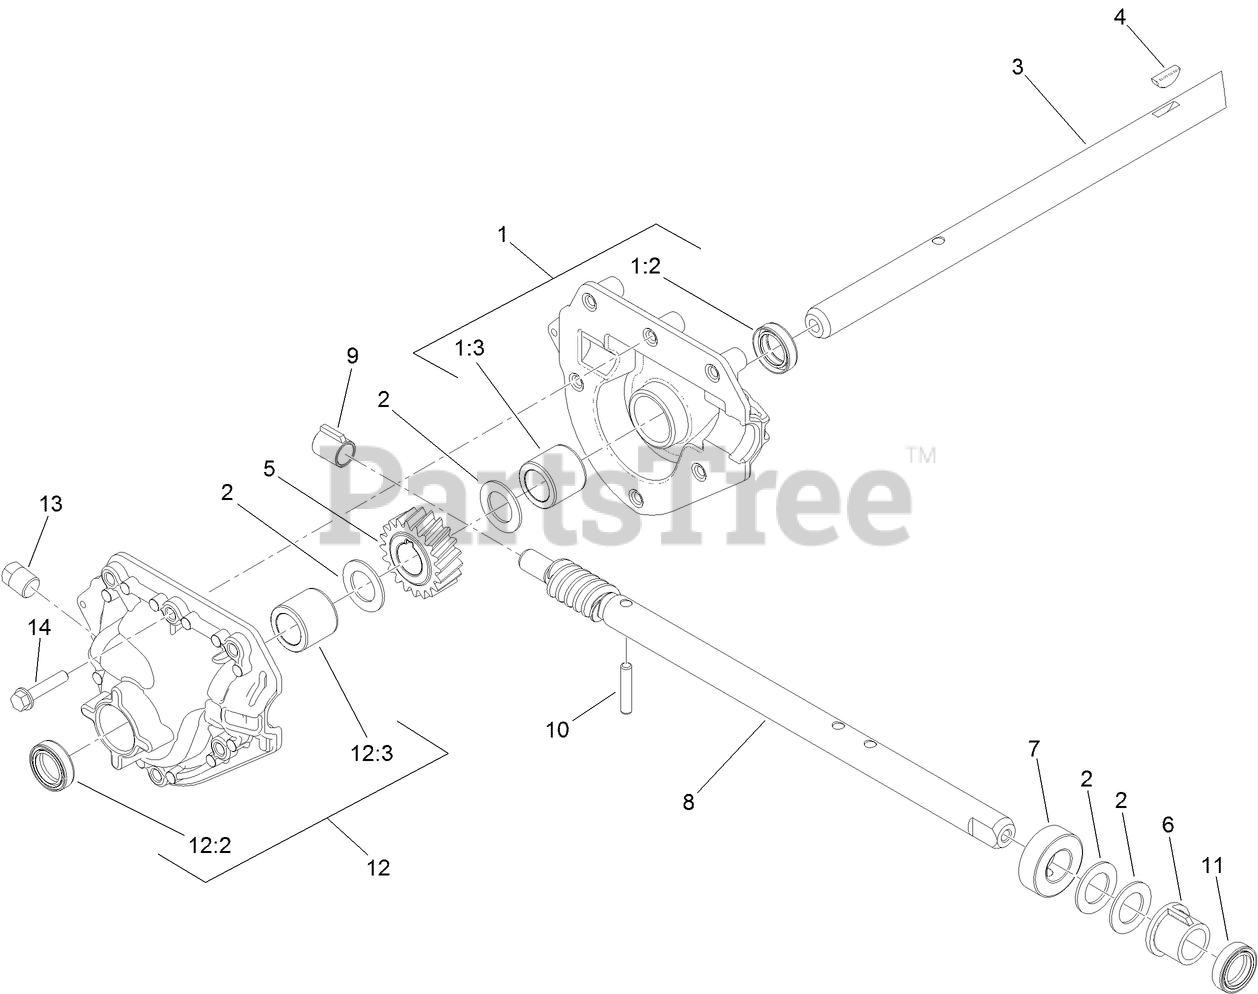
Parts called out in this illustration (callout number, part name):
1	RH AUGER GEARCASE ASM
1:2	SEAL-SHAFT
1:3	BUSHING-SLEEVE
2	WASHER-THRUST
3	SHAFT-OUTPUT, AUGER
4	KEY-WOODRUFF
5	GEAR-HELICAL, 20 TOOTH
6	BUSHING-INPUT
7	COLLAR-THRUST
8	SHAFT-IMPELLER, ROLLED
9	BUSHING-WORM
10	PIN-DOWEL
11	SEAL-SHAFT
12	LH AUGER GEARCASE ASM
12:2	SEAL-SHAFT
12:3	BUSHING-SLEEVE
13	PLUG-PIPE, SQH
14	SCREW-HWHTF
